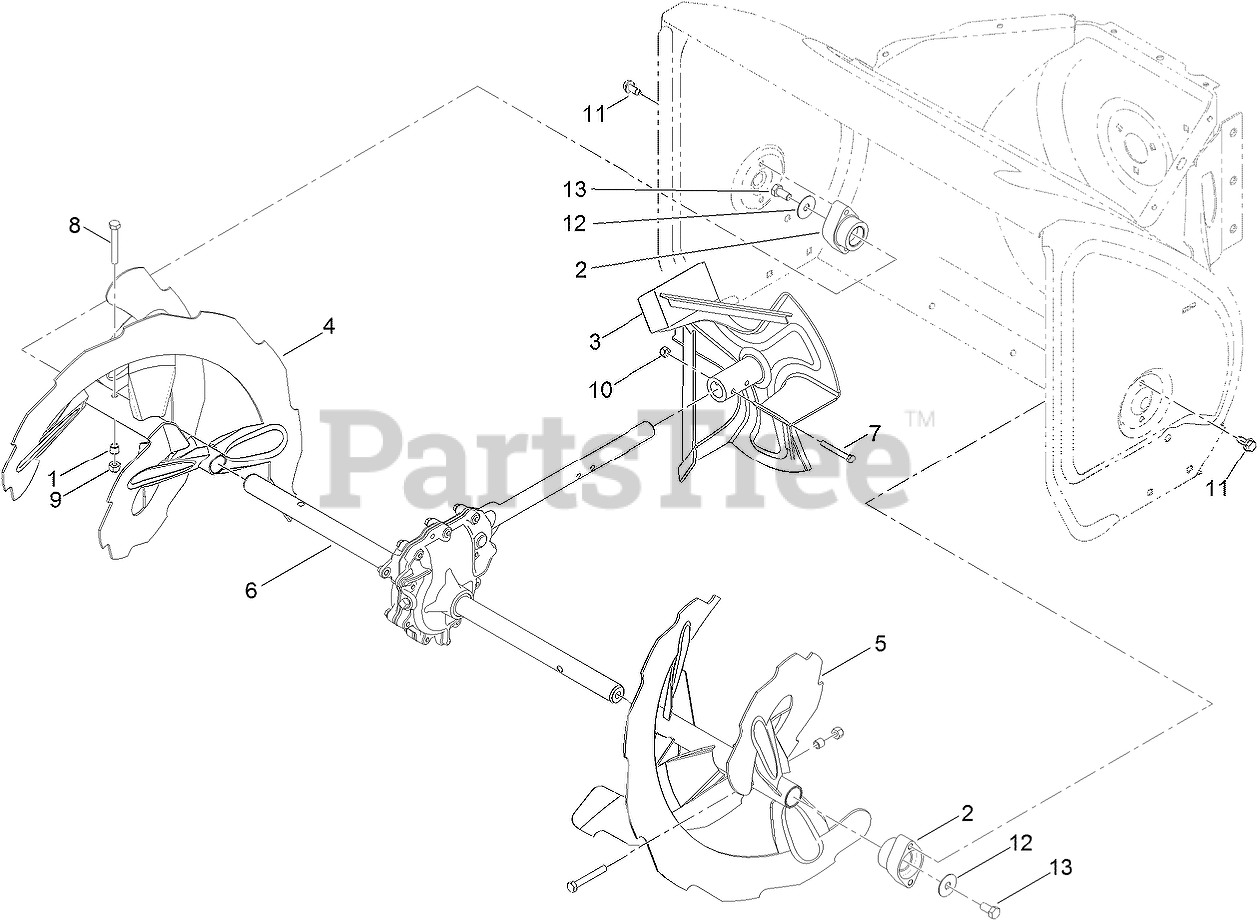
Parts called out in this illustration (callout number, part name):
1	SPACER
2	BEARING-AUGER
3	IMPELLER ASM
4	RH AUGER ASM
5	LH AUGER ASM
6	26 INCH AUGER GEARCASE ASM
7	SCREW-HH
8	SCREW-HH
9	NUT-LOCK, NI
10	NUT-LOCK, NI
11	SCREW-HWHTF
12	WASHER
13	SCREW-HH
